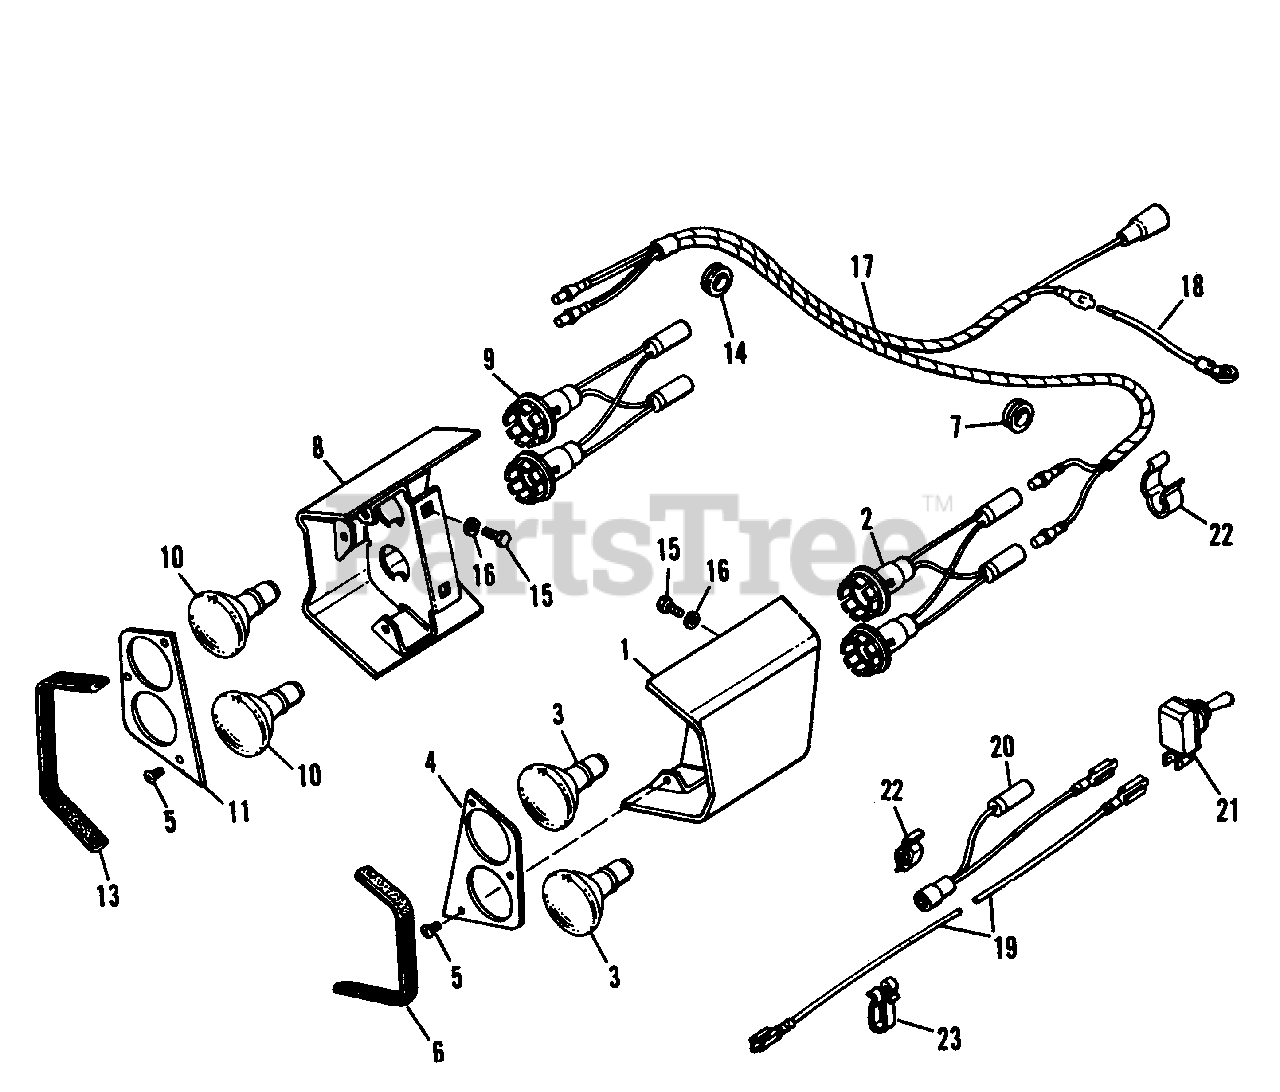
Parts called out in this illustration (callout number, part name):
1	SHROUD & PLATE ASSEMBLY L.H.
2	LAMP SOCKET & WIRE ASSEMBLY
3	HEADLIGHT
4	PLATE, Front
5	SCREW, Thread Forming, #12-24 x 1/2" lg.
8	SHROUD & PLATE ASSEMBLY R.H.
9	LAMP SOCKET & WIRE ASSEMBLY
10	HEADLIGHT
11	PLATE, Front
12	SCREW, Thread Forming #12-24 x 1/2" lg.
15	SCREW, Hex, 1/4"-20 x 3/4" lg.
16	LOCKWASHER, 1/4"
17	HARNESS ASSEMBLY
18	WIRE, Headlight to Ground
19	WIRE ASSEMBLY, Light Switch
20	WIRE ASSEMBLY
21	SWITCH, Toggle
22	CABLE Clip, Tinnerman
23	CABLE Clip, Tinnernnan
